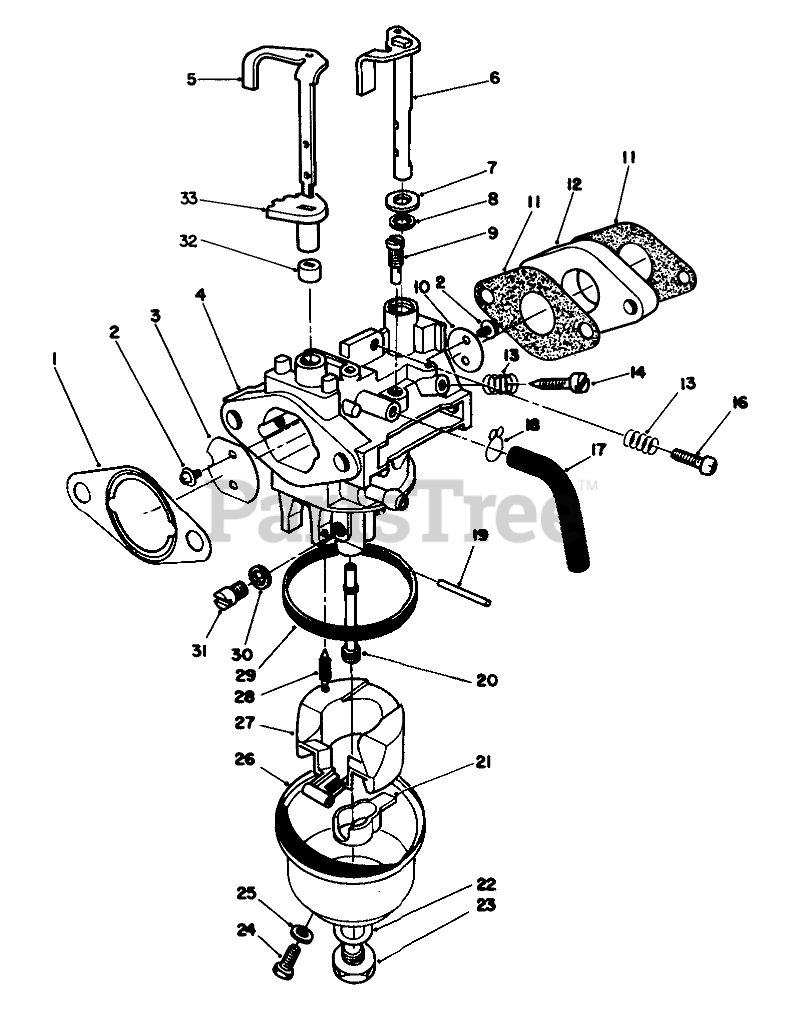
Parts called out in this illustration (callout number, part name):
1	GASKET F/W ENGINE
2	Screw
3	VALVE
4	Body-Carburetor
5	Shaft-Choke Valve
6	SHAFT
7	WASHER
8	Seal-Throttle Shaft
9	PILOT JET
10	VALVE
11	Gasket-Carburetor
12	CARB INSULATOR
13	SPRING-PILOT SCREW
14	ADJUSTER
16	SCREW
18	CLAMP
19	Pin
20	NOZZLE
21	SPACER
22	GASKET
23	SCREW
24	SCREW
25	GASKET
27	FLOAT
28	NEEDLE
29	FLOAT BOWL GASKET
30	SPACER
31	MAIN JET
32	LOWER CHOKE RING
33	UPPER CHOKE RING
